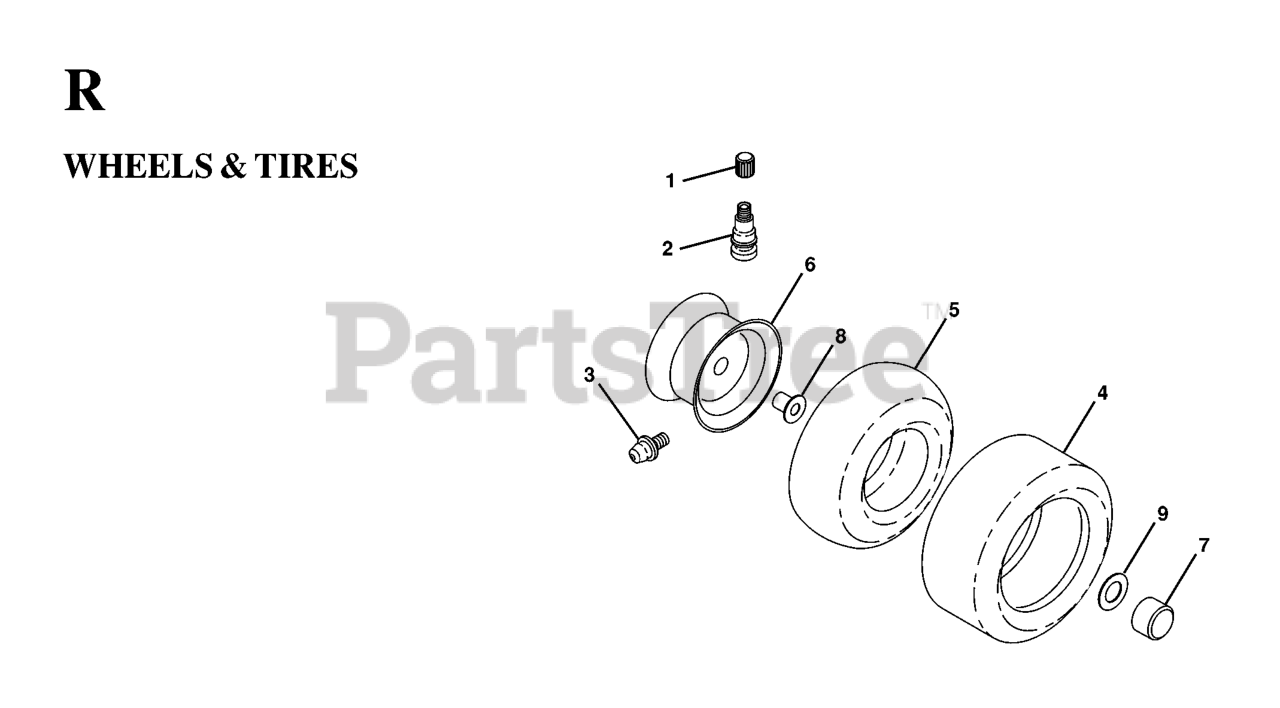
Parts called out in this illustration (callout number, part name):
2	VALVE STEM LT
3	FITTING LT
4	TIRE FRONT 15X6-6
5	TUBE.5.3/4.5/6
5	TUBE.16X6.5/7.5-8
6	RIM
6	RIM REAR 8"
7	CAP.HUB.FRONT.LT.BLACK
8	BEARING T
